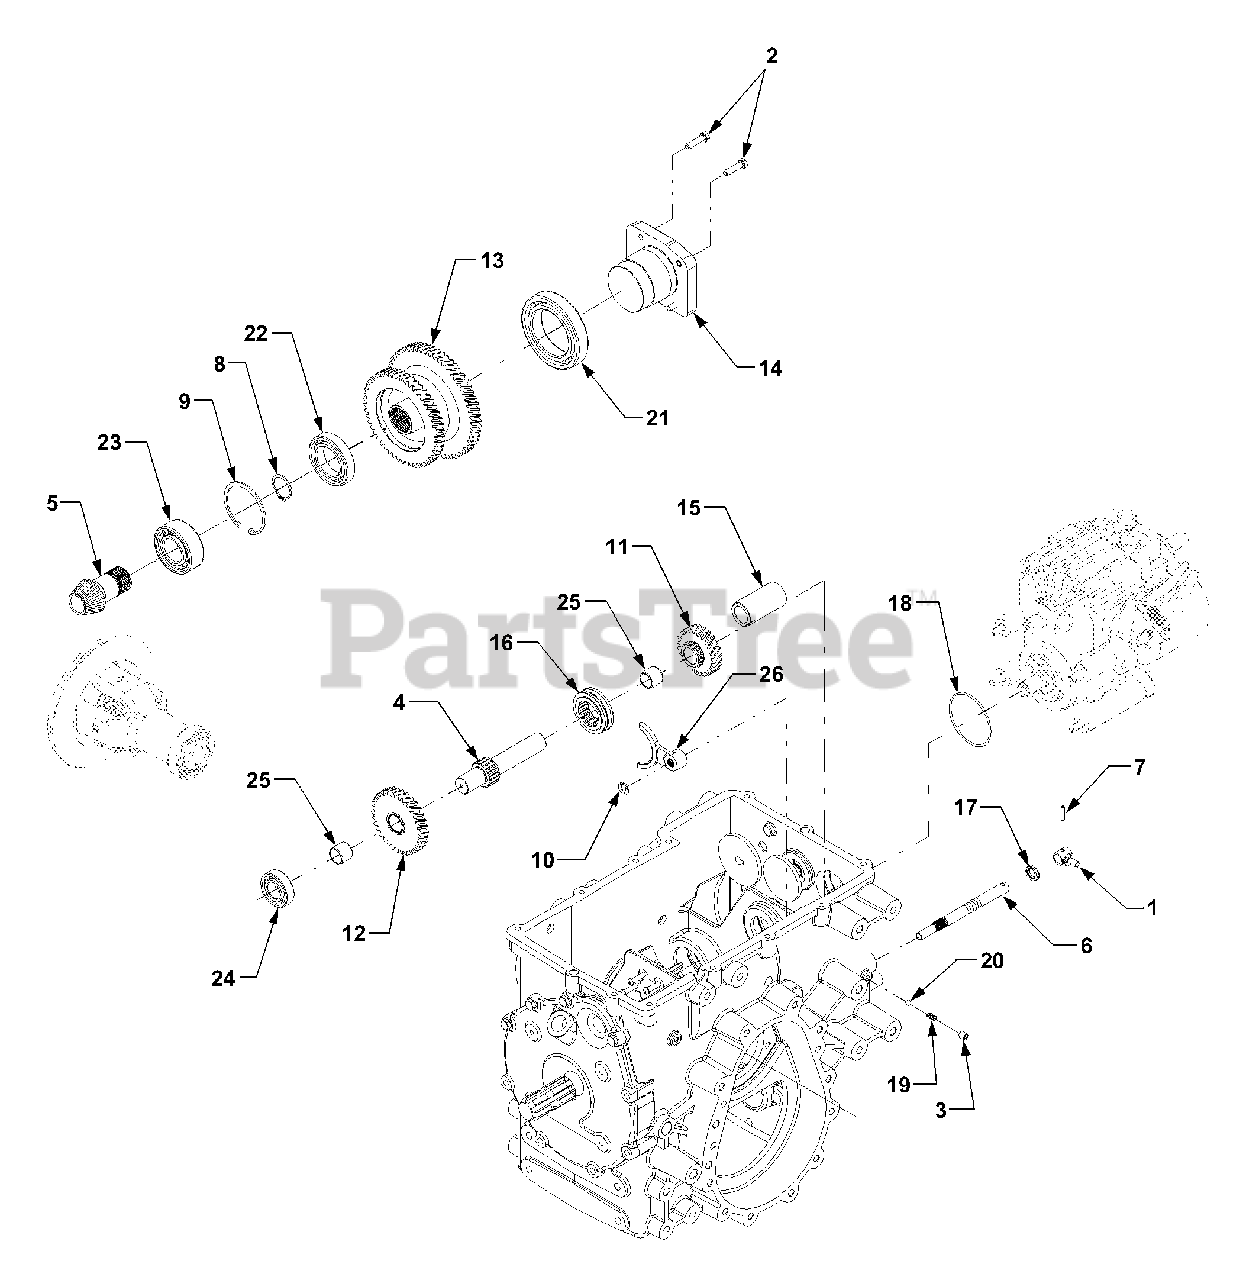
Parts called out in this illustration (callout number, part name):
1	Pin Assembly, 2 Speed
2	Screw, Hex Cap Lock, 5/16-18 x 1.25 GR5
3	Screw, Cup Set, 5/16-18 x 3/8
4	Shaft, Motor
5	Shaft, Pinion, 16T
6	Shaft, 2 Speed Actuator
7	Pin, Spirol, 3/16 x .875
8	Ring, Retaining
9	Ring, Retaining
10	Clip, Rotor
11	Gear, Drive Pinion, LO 24T:17T
12	Gear, Drive Pinion, HI 33T:17T
13	Gear, Drive, LO:59T; HI 50T
14	Cover, Front
15	Spacer, Drive
16	Collar, 2 Speed
17	Seal, Oil
19	Spring, Detent
20	Ball, Detent
21	Bearing, Ball
22	Bearing, Ball
23	Bearing, Angular Contact Ball
24	Bearing, Ball
25	Bearing, Sleeve
26	Yoke, 2 Speed
